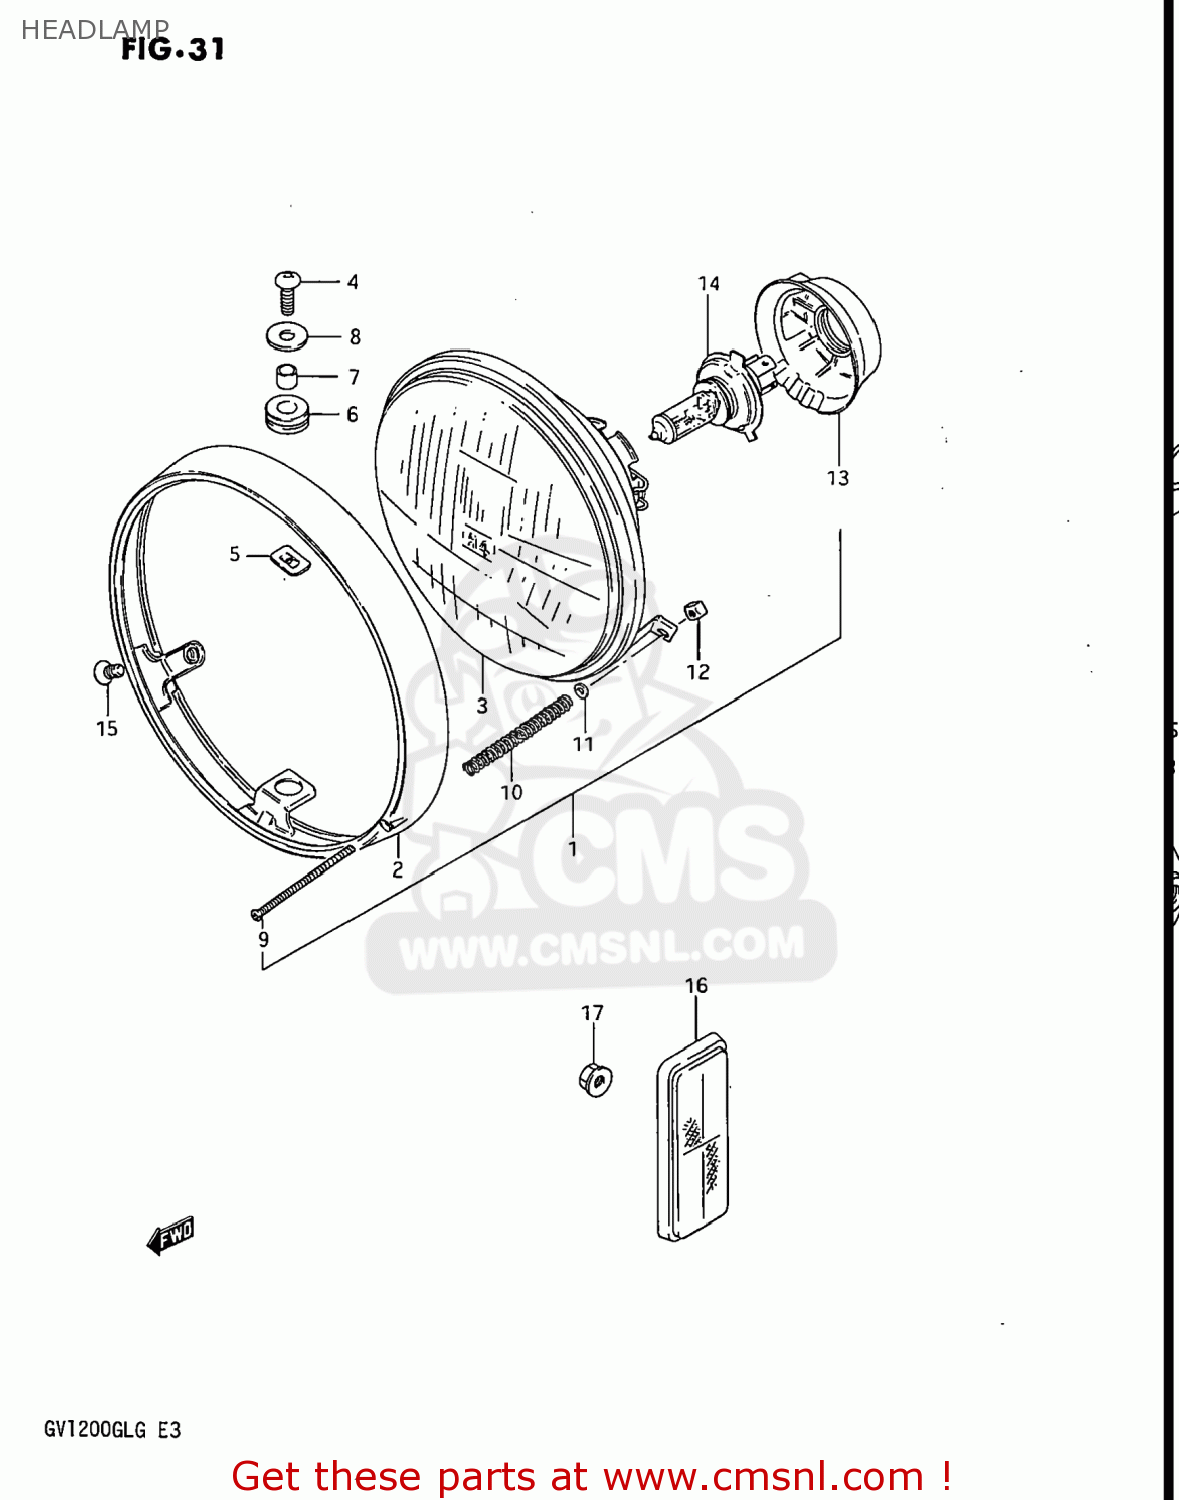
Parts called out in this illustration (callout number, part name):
1	HEADLAMP ASSY
2	RIM,HEAD LAMP
3	LAMP UNIT
4	SCREW(5X14)
5	NUT
6	CUSHION
7	SPACER
8	WASHER
9	SCREW,HEADLAMP ADJUST
10	SPRING,HEADLAMP ADJUST
11	WASHER
12	NUT
13	COVER,SOCKET
14	BULB(12V60/55W,H4)
15	SCREW(5X12)
16	REFLEX REFLECTOR,FR SIDE
17	NUT
